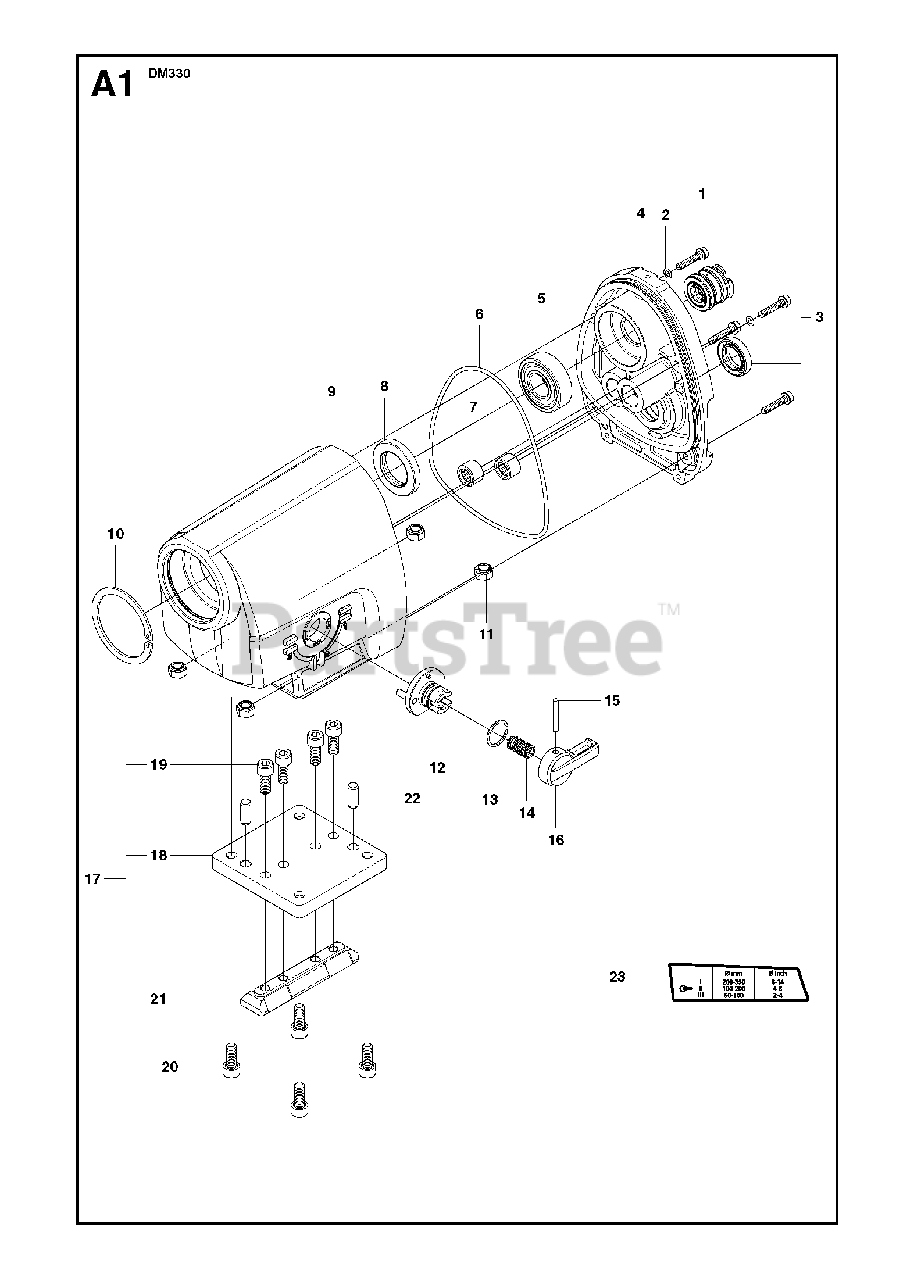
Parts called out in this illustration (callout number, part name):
1	SCREW IHSCFM
5	BALL BEARING
7	NEEDLE BEARING
11	HEXAGON LOCKING NUT
15	PARALLEL PIN
17	MOTOR BRACKETIncl. 18, 19 and 21
22	PARALLEL PIN
23	LABELLow speed version
23	LABELHigh speed version
